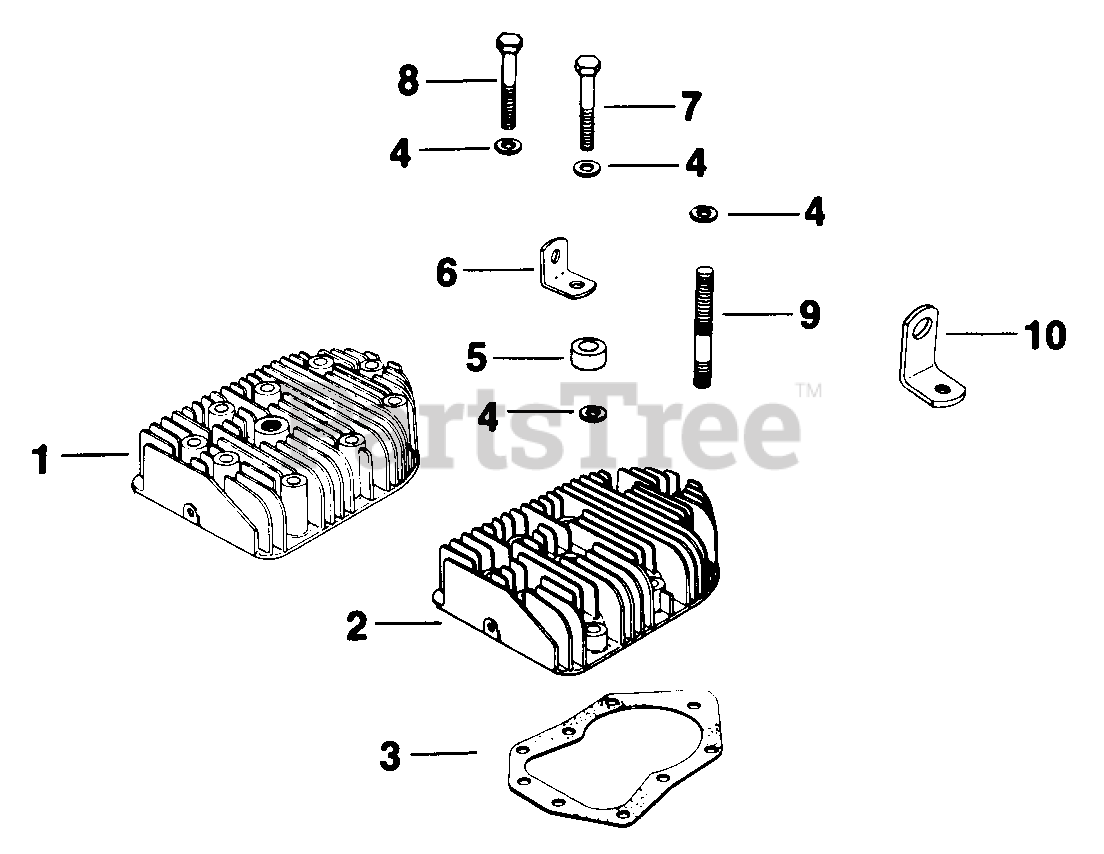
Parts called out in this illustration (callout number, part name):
2	HEAD
3	GASKET - USE 47 041 15-S
4	WASHER, FLAT 13/32"
5	SPACER USE 25 112 14-S
6	STRAP - USE 47 445 02
7	SCREW - DISCONTINUED
8	SCREW, MACH 3/8-16X1-1/2" USE 25 086 115-S
9	STUD
